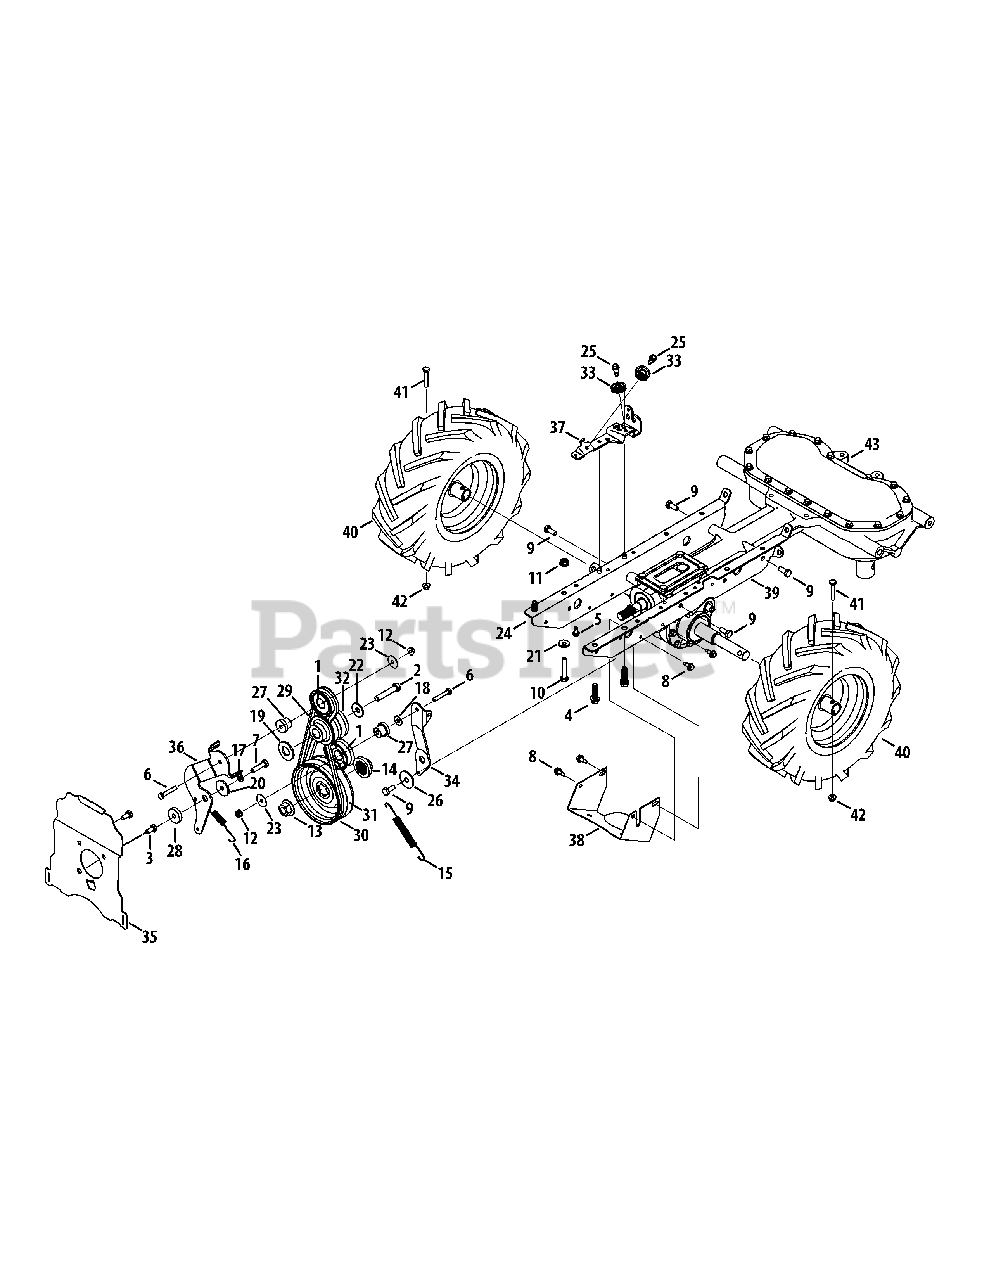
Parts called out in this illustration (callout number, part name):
1	Idler Pulley Assembly, 1.917 OD
2	Hex Head Screw, 3/8-24 x 2.00
3	Hex Head Screw, 5/16-24 x .625
4	Screw, 3/8-16 x 1.250
5	Screw, 1/4-20 x 0.500
6	Hex Head Screw, 1/4-20 x 1.50
7	Hex Head Screw, 5/16-24 x 1.25
8	Self Tapping Screw, 1/4-14 x .625
9	Hex Head Screw, 5/16-18 x .75, Patch
10	Hex Cap Screw, 5/16-18 x 1.75
11	Flangelock Nut, 5/16-18, B&S
12	Flangelock Nut, 1/4-20
13	Flange Nut, 9/16-18
14	Pulley Hub, 5/8 SPLINE
15	Extension Spring, .480 OD x 5.00 LG
16	Extension Spring, LT5 PTO
17	Washer, Lock, 5/16
18	Washer, Flat, .28 x .74 x .063
19	Washer, Flat, .760 x 1.50 x .120
20	Washer, Flat, .330 x 1.25 x .120
21	Washer, .396 x 1.140 x .095, B&S
22	Washer, Bell, .396 x 1.140 x .095
23	Washer, Flat, .265 x 1.0 x .030
24	RH Mount Frame
25	Screw, Shoulder, 1/4-28 x .342 x .335
26	Forward Idler Pivot Spacer
27	Spacer, Shoulder, .260 x .785 x .538
28	Reverse Idler Pivot Spacer
29	V Belt, 3L x 29.125 LG
30	V Belt, 4L x 25.4 LG
31	Transmission Pulley
32	Engine Pulley, 3L & 4L
33	Cable Roller
34	Forward Idler Bracket
35	Cover Mounting Plate
36	Reverse Idler Bracket
37	Pulley Mounting Bracket
38	Pulley Shield
39	LH Mount Frame
40	Wheel Assembly, 13 x 5 x 6
40	Rim Only, Beige
41	Hex Head Screw, 1/4-20 x 1.5
42	Flangelock Nut, 1/4-20
43	Transmission Assembly
